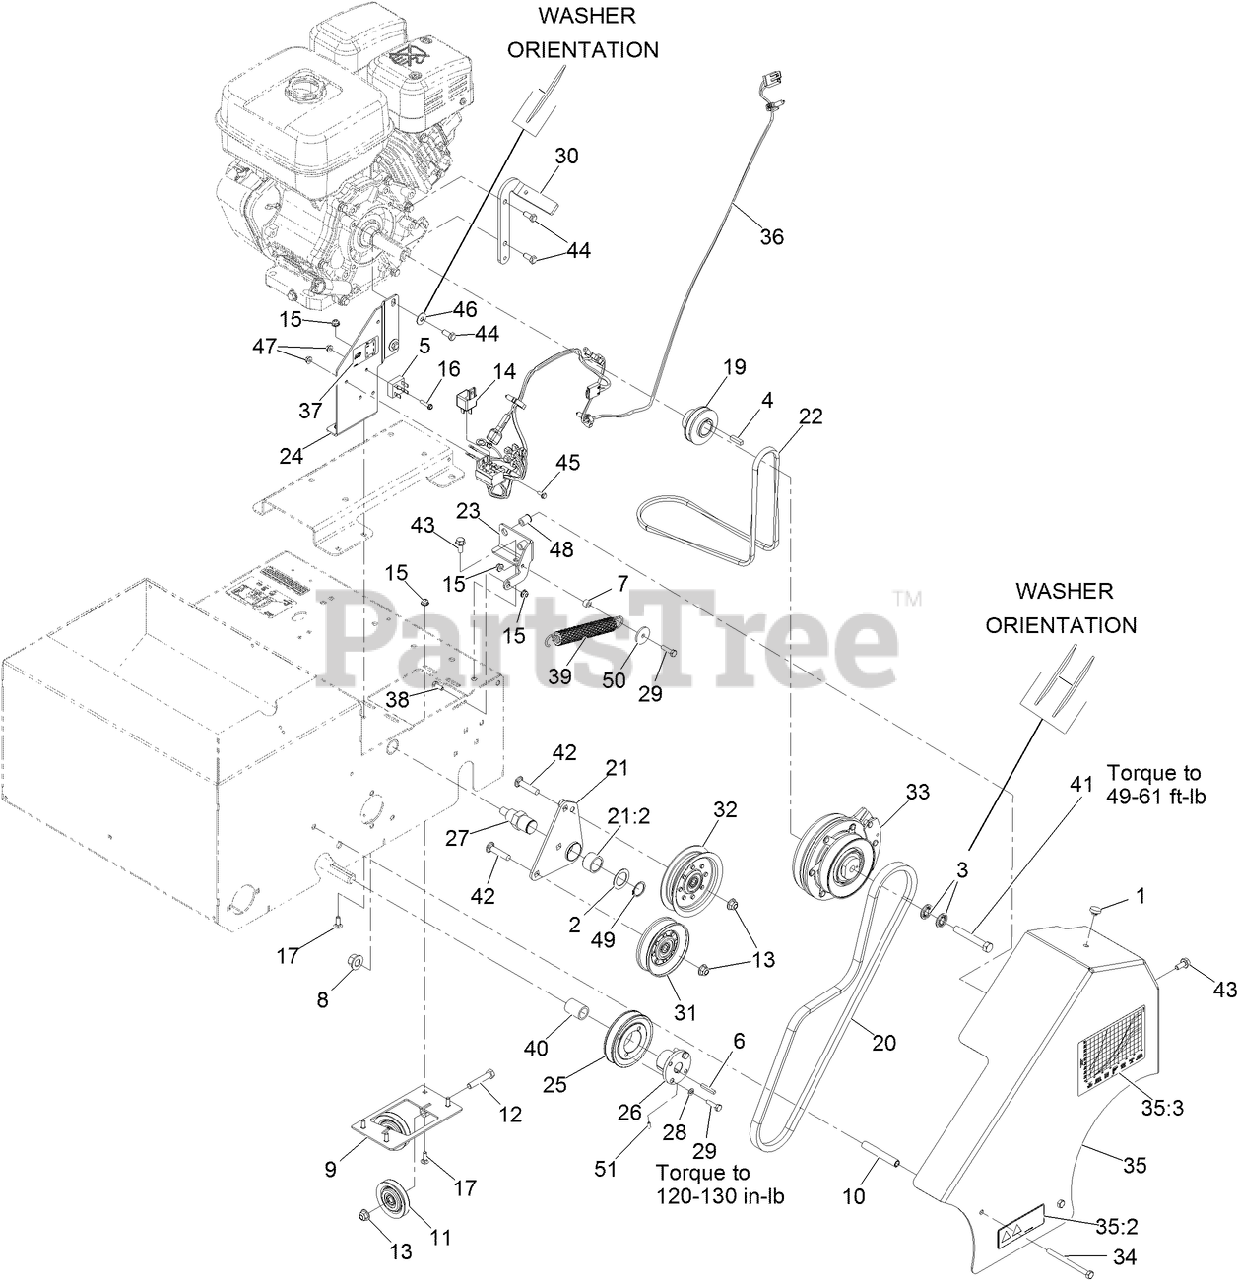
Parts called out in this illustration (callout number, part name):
1	BUMPER
2	WASHER-SPACER
3	WASHER-SPRING
5	RECTIFIER-BRIDGE
6	KEY-SQUARE
7	Spacer
8	NUT-LOCK
9	PULLEY-TENSION
10	SPACER-KICKSTAND, LONG
11	PULLEY-IDLER
12	SCREW-HH
13	NUT-HF, NI
15	NUT-HF
16	SCREW-HWH
17	BOLT-CARR
19	PULLEY-MULE DRIVE
20	BELT-SEEDER, CLUTCH
21	IDLER ARM ASM
21:2	BUSHING
22	BELT-MULE DRIVE
23	BRACKET-SPRING
24	SUPPORT-ENGINE
25	SHEAVE-TAPER LOCK
26	BUSHING-TAPER LOCK
27	PIVOT-IDLER
28	WASHER-LOCK
29	SCREW-HH
30	STOP-CLUTCH
31	PULLEY-IDLER V
32	PULLEY-IDLER FLAT (4.06-INCH)
33	CLUTCH-ELECTRIC
34	SCREW-HH
35	BELT GUARD ASM
35:2	DECAL-DANGER
35:3	DECAL-SEED GRAPH
36	HARNESS-SLICER/SEEDER
37	DECAL-BRIDGE RECTIFIER
38	SCREW-HH
39	SPRING-EXTENSION
40	SPACER
41	SCREW-HH
42	SCREW-CARR
43	SCREW-HHF
44	SCREW-HH
45	SCREW-HWH
46	WASHER-BELLEVILLE
47	NUT-LOCK, FLANGE
48	NUT-INSERT
49	Ring-Retaining
50	WASHER
51	SCREW-SET, HS
